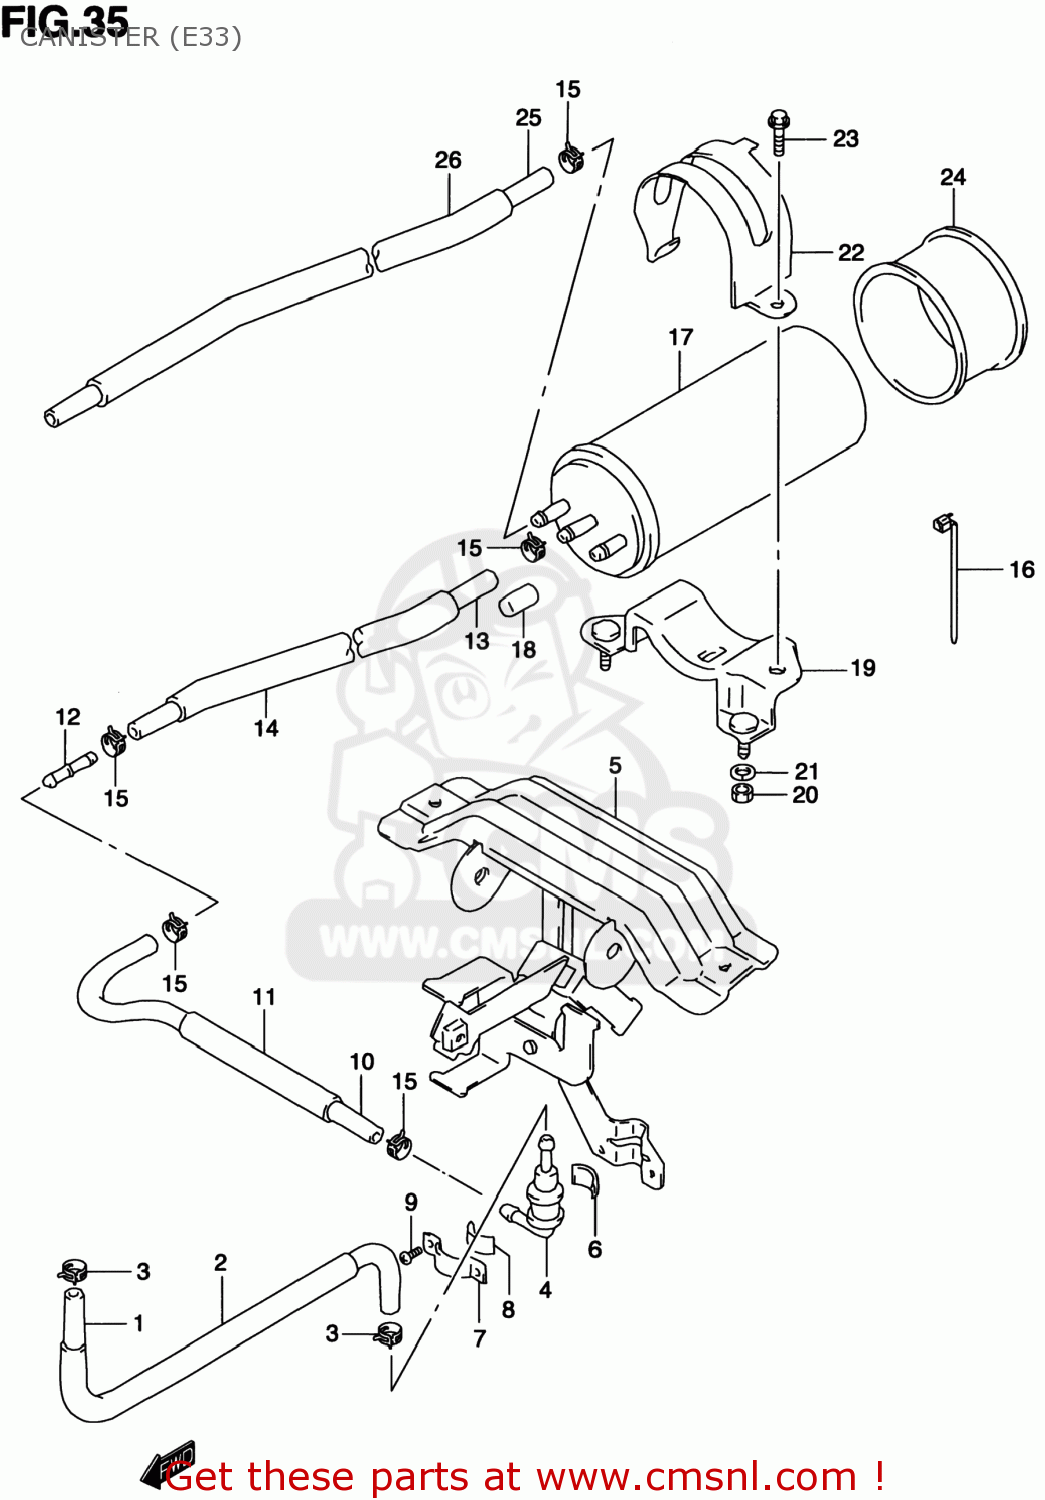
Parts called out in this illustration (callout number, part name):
1	HOSE,TANK & BREATHER VALVE
2	PROTECTOR(14.5X15.5X600)
3	CLIP
4	VALVE,FUEL TANK BREATHER
5	BRACKET,FUEL TANK RR
6	CUSHION
7	PLATE,FUEL TANK BREATHER NO.2
8	CUSHION
9	SCREW
10	HOSE(5.4X11.4X600)
11	PROTECTOR(14.5X15.5X600)
12	UNION
13	HOSE(5.4X11.4X600)
14	PROTECTOR(14.5X15.5X600)
15	CLIP
16	CLAMP(L:165)
17	CANISTER ASSY,CHARCOAL
18	CAP,OD:11.5
19	BRACKET,CANISTER
20	NUT
21	WASHER
22	HOLDER,CANISTER
23	SCREW 6X12
24	CUSHION,CANISTER
25	HOSE(5.4X11.4X1000)
26	HOSE
27	CLIP
